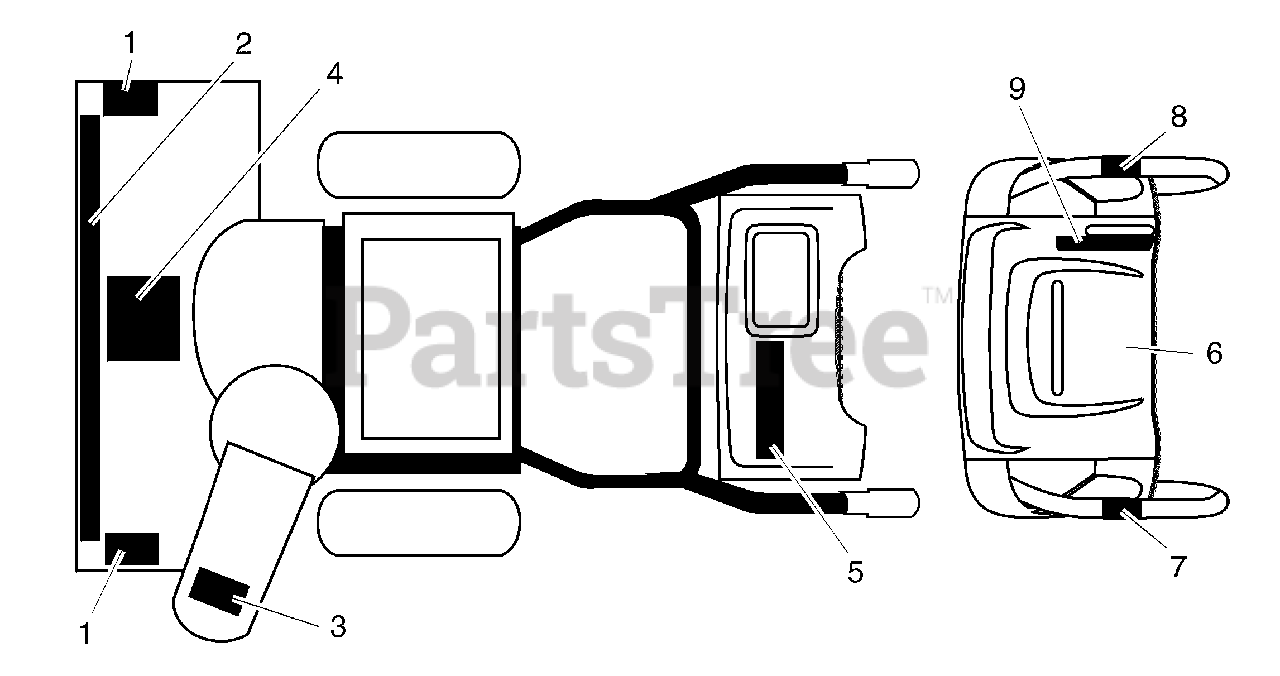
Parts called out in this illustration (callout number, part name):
1	DECAL, DANGER
2	DECAL, HUSQ
3	DECAL, DANGER, DEFLECTOR
4	DECAL, DANGER
5	DECAL, HUSQ
6	DECAL, INSTRUCTION
7	DECAL, TRACTION LEVER
8	DECAL, AUGER LEVER
9	DECAL, SPEED CONTROL
9	OWNER’S MANUAL, ENGLISH
9	OWNER'S MANUAL, FRENCH
